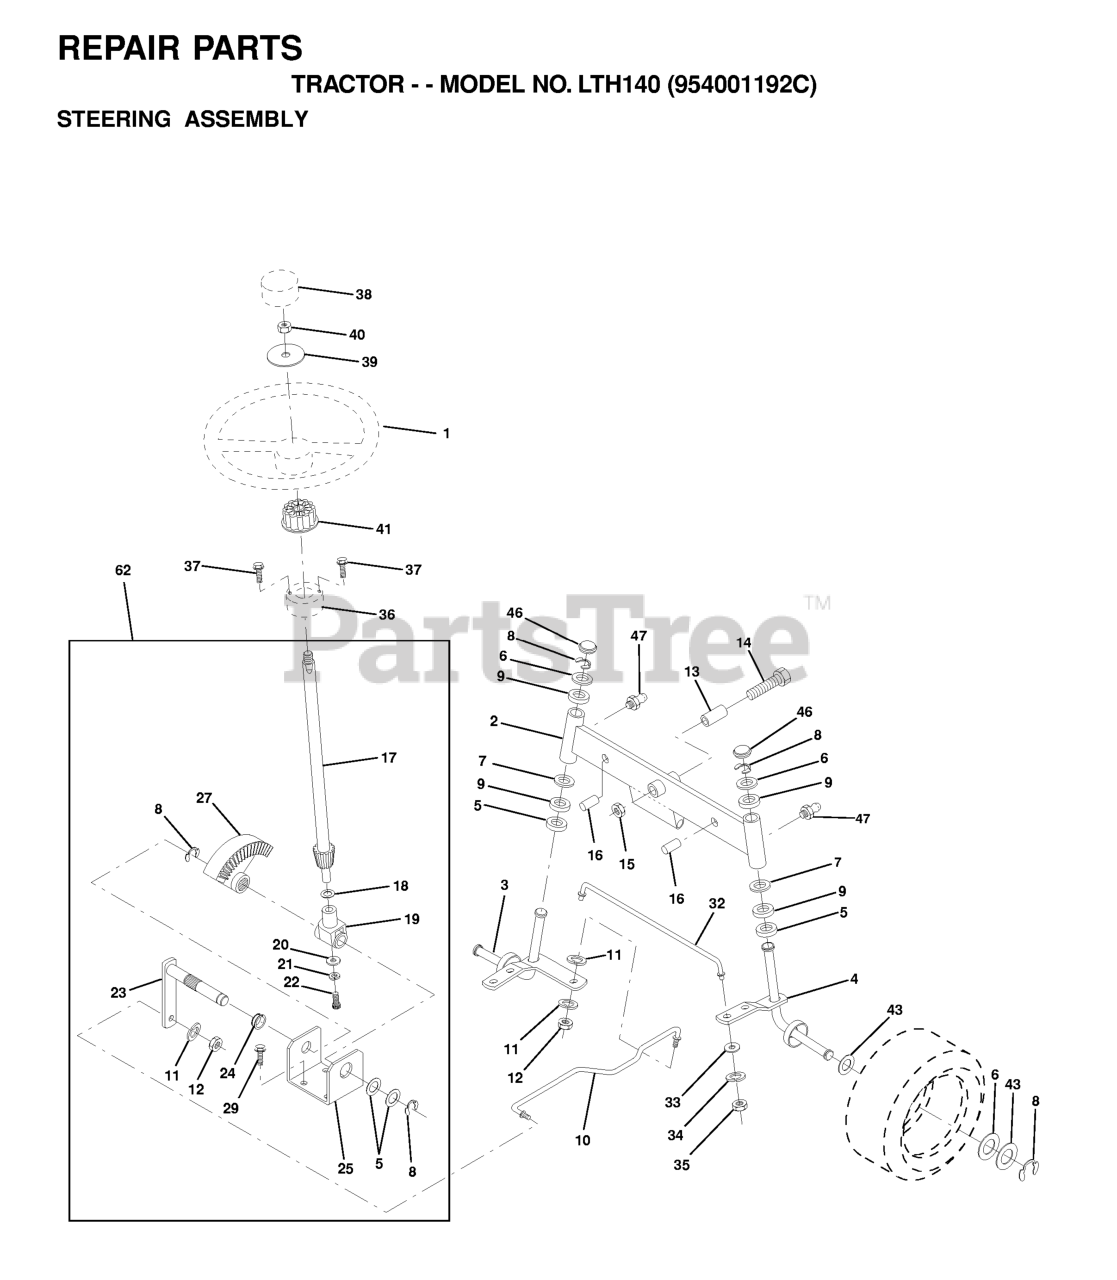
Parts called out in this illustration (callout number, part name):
1	STEERING WHEEL
3	SPINDLE LH
4	SPINDLE RH
5	THRUST WASHER
9	BRNG T
10	LINK.DRAG.SOL.BALL JT.20.064
11	WASHER, LOCK 3/8
12	NUT
13	BEARING
14	Bolt, Hex Head 5/8-11 x 3-1/2
15	NUT-LOC,FLANGE LT
17	STEERING SHAFT
18	THRUST WASHER
19	SHAFT,SUPPORT
20	WASHER
21	LOCKWASHER
22	SCREW,SPECIAL
23	SHAFT PITMAN
24	NYLINER T (7283A)
25	BRKT,STEERING
27	GEAR.SECTOR
29	SCREW
32	TIE ROD
33	WASHER M
34	WASHER.LOCK.HVY.HLCL.SPR.5/16
35	LOCKNUT
36	BUSHING STRG 3/4
38	INSERT,STR WHEEL
40	NUT.HEX.1/2-20
41	ADAPTER LT
46	CAP.SPINDLE.BLACK
47	ZERK M
62	STEERING KIT
